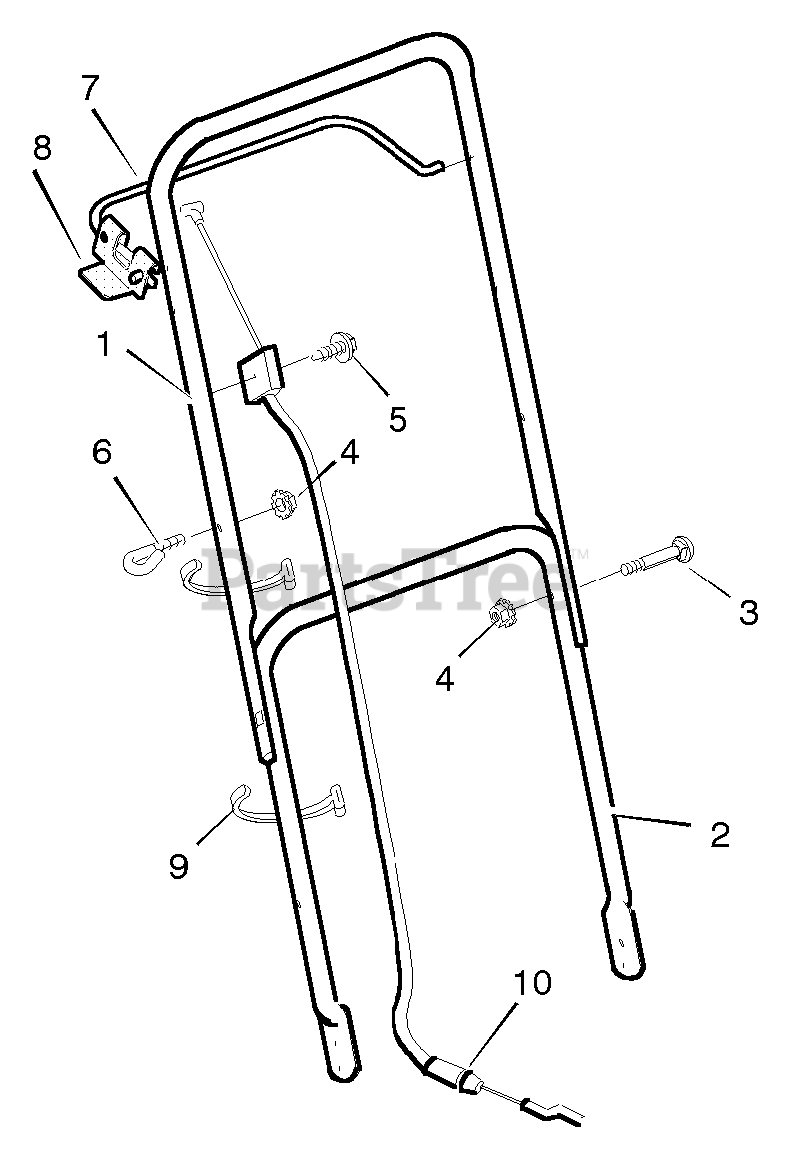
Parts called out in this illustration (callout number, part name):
1	Handle, Upper - Straight (Gray)
2	Handle, Lower (Gray)
4	Locknut
6	GUIDE, ROPE
7	Engine Stop Lever - Straight
8	Bracket, Stop Lever
9	Fastener, Cable
10	Engine Stop Cable
